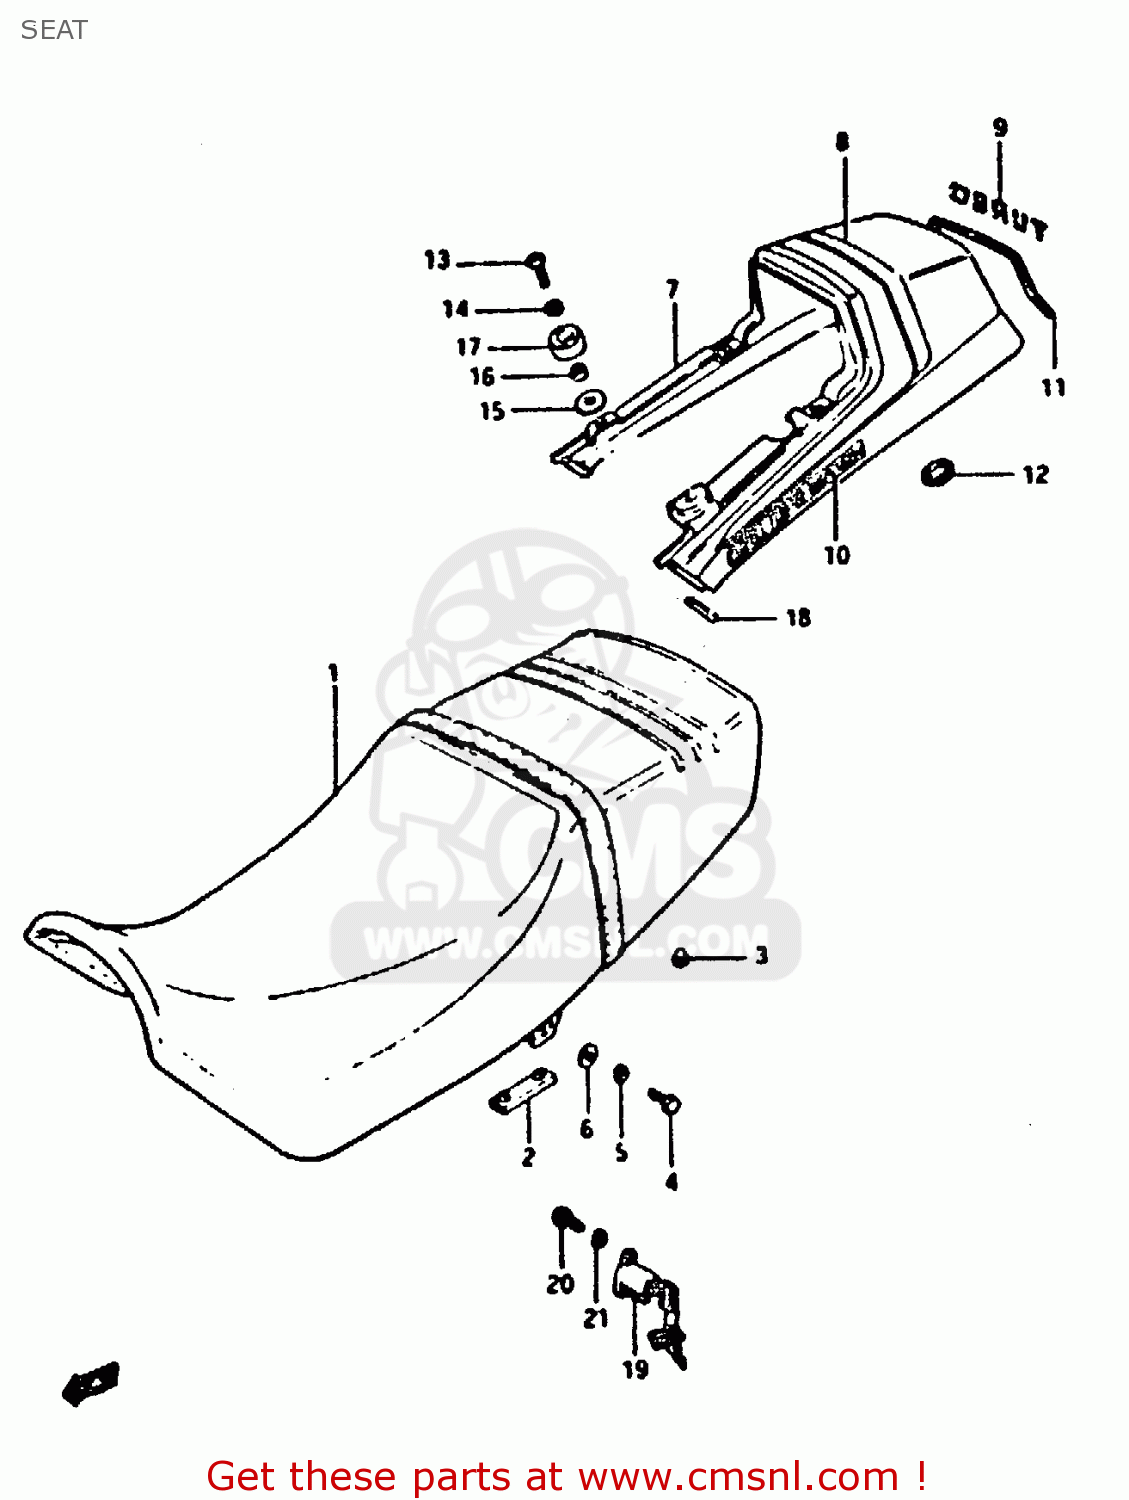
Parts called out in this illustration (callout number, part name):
1	SEAT ASSEMBLY
2	CUSHION
3	CUSHION
4	BOLT
5	LOCK WASHER
6	WASHER
7	BOX ASSEMBLY,SEAT TAIL
8	TAPE SET,BOX SEAT TAIL
9	EMBLEM (TURBO)
10	EMBLEM,FULL FLOATER
11	MOLDING,SEAT TAIL COVER
12	CUSHION
13	SCREW
14	LOCK WASHER
15	WASHER (6.5X24X1.6)
16	SPACER
17	CUSHION,COVER
18	CUSHION, FRONT
19	LOCK SET
20	BOLT 6X11
21	LOCK WASHER
